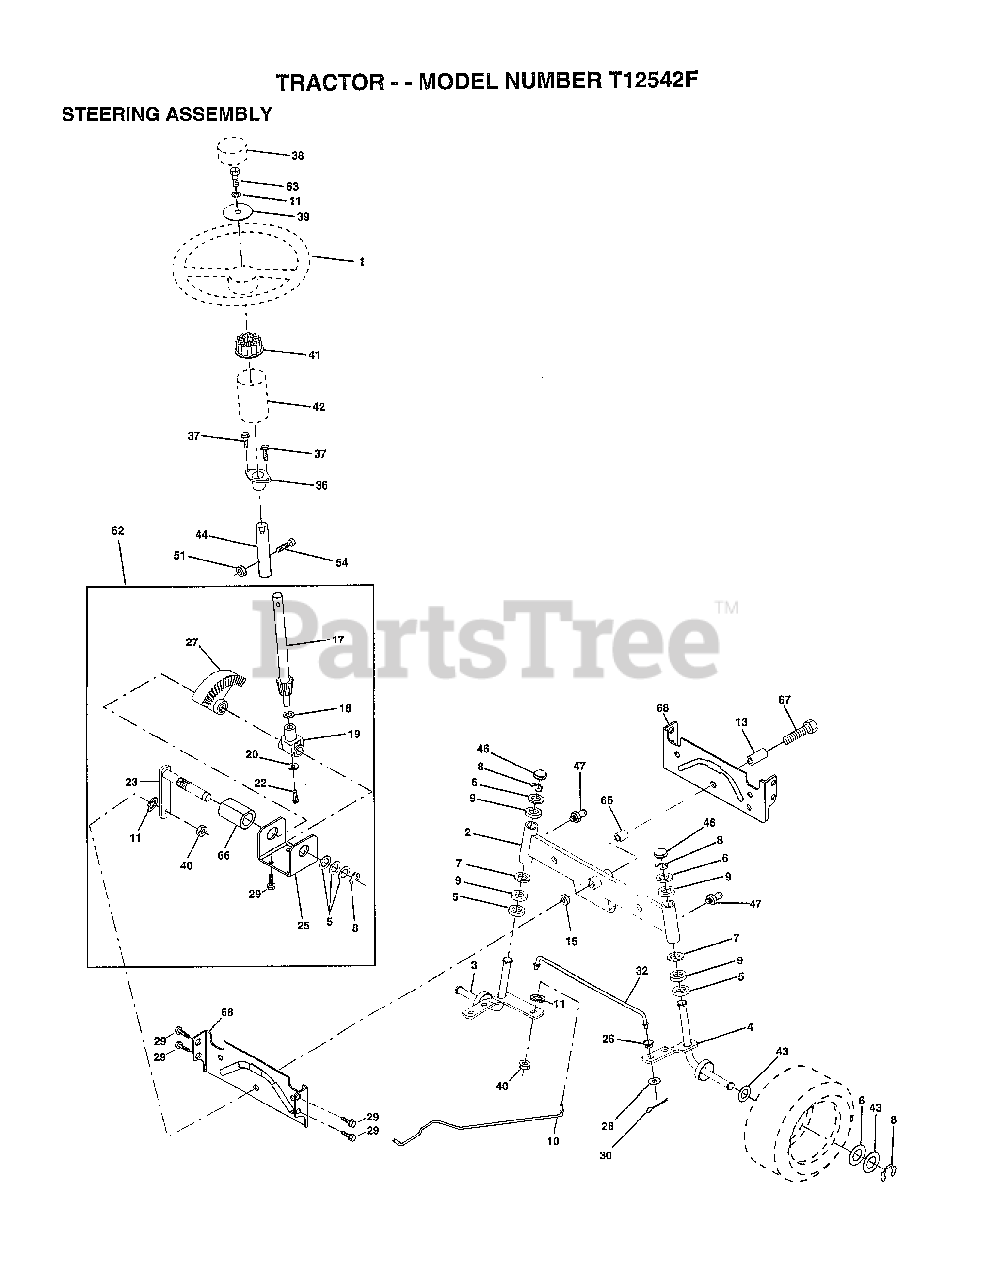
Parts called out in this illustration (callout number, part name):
2	AXLE ASM
3	SPINDLE.ASM.LH
4	"SPINDLE ASM,RH"
5	WASHER .T
6	WASHER
7	WASHER
8	RING
9	COL. SRTG. BEAR.
10	DRAGLINK-STAMPED
11	LOCKWASHER
13	BEARING AXLE
15	"NUT-LOC,FLANGE LT"
17	SHAFT ASM STEERIN
18	THRUST WASHER
19	SUPPORT.SHAFT
22	SCREW HEX SOC1/4-
25	BRKT-STEERING
26	BUSHING.DRAGLINK
27	GEAR SECTOR
28	WASHER
29	SCREW
30	COTTER PIN
32	TIE ROD
36	BUSHING.STEERING
37	"SCREW-TT,10-32 FL"
38	ST WHL INSERT CAP
39	WASHER T
40	GRIPCO NUT
41	ADAPTER LT
42	BOOT.STEER.PL
43	WASHER
44	EXT SHAFT STEERIN
46	CAP
47	ZERK M
51	NUT
54	BOLT
62	KIT STEERING ASM
63	BOLT
65	SPACER AXLE
66	"BEARING-ARM,PITMA"
67	BOLT
68	BRACE AXLE
